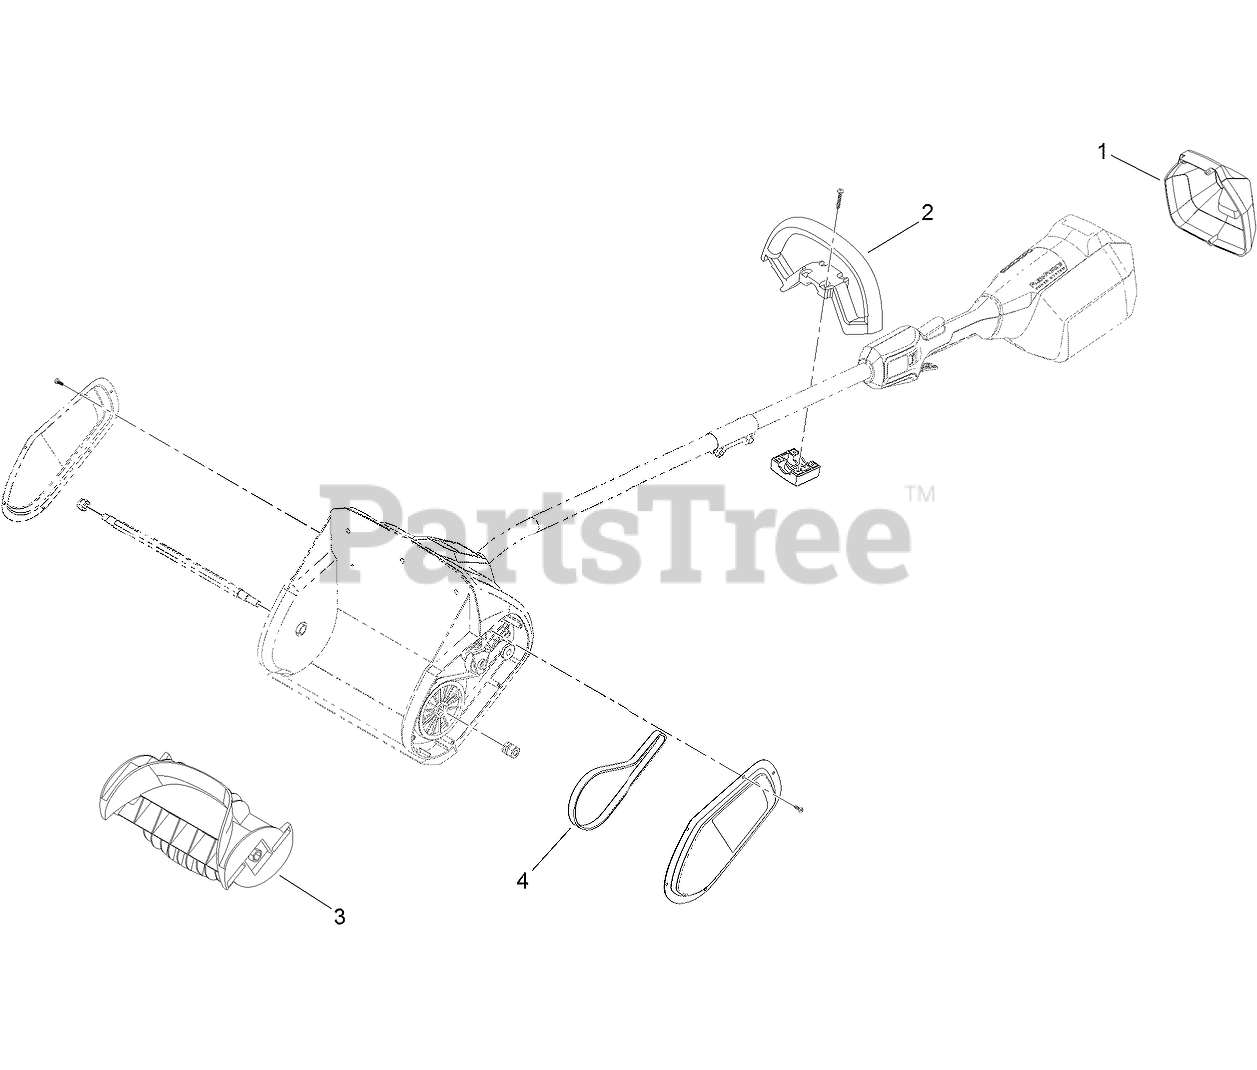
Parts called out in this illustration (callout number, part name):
1	COVER-BATTERY
2	HANDLE-TRIMMER
4	BELT-DRIVE
